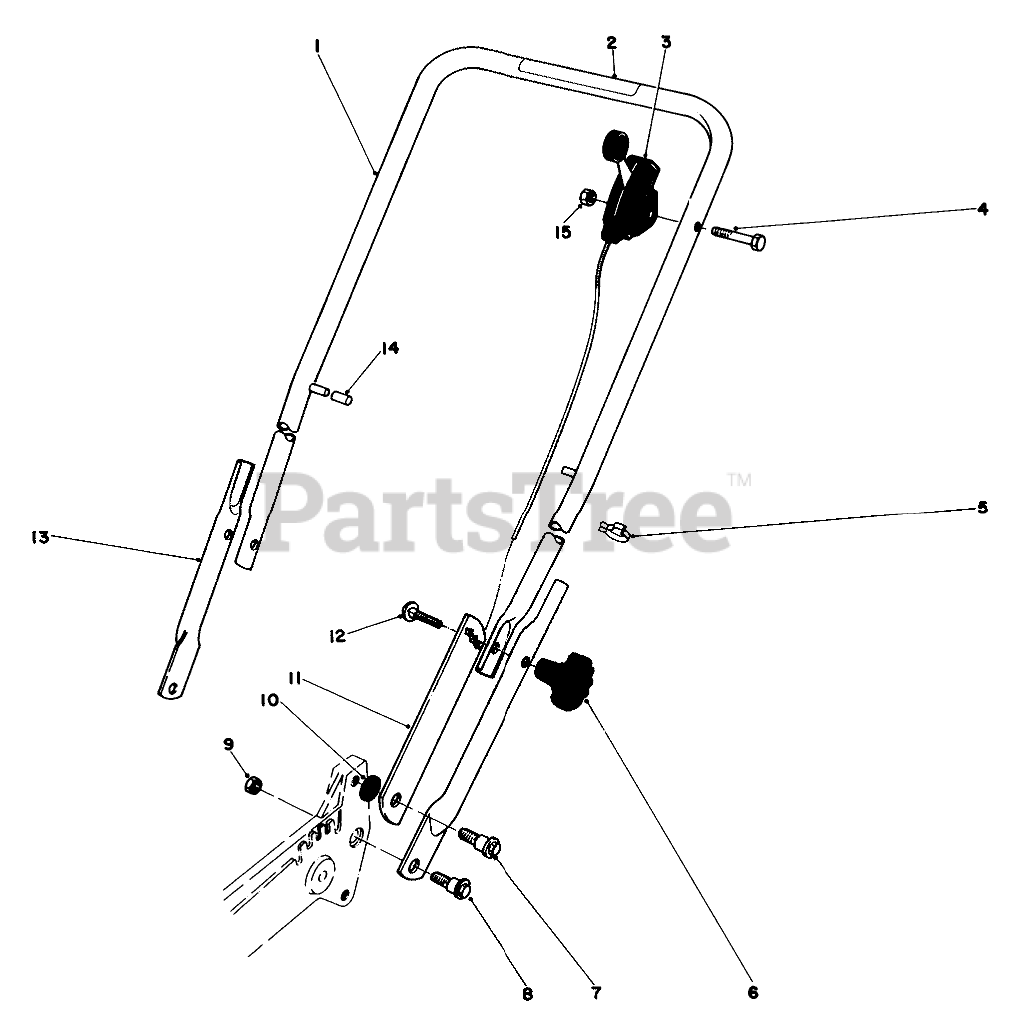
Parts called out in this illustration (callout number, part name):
1	Upper Handle (Incl. Ref. #2)
2	Decal
3	Throttle Control
4	SCREW-HH
5	BOWDEN CLIP
7	Screw
8	SCREW-SHOULDER
9	Nut
10	Spacer Handle Latch
11	HANDLE LATCH
12	SCREW-CARR
13	LOWER HANDLE
14	CAP-VINYL
15	NUT-LOCK
